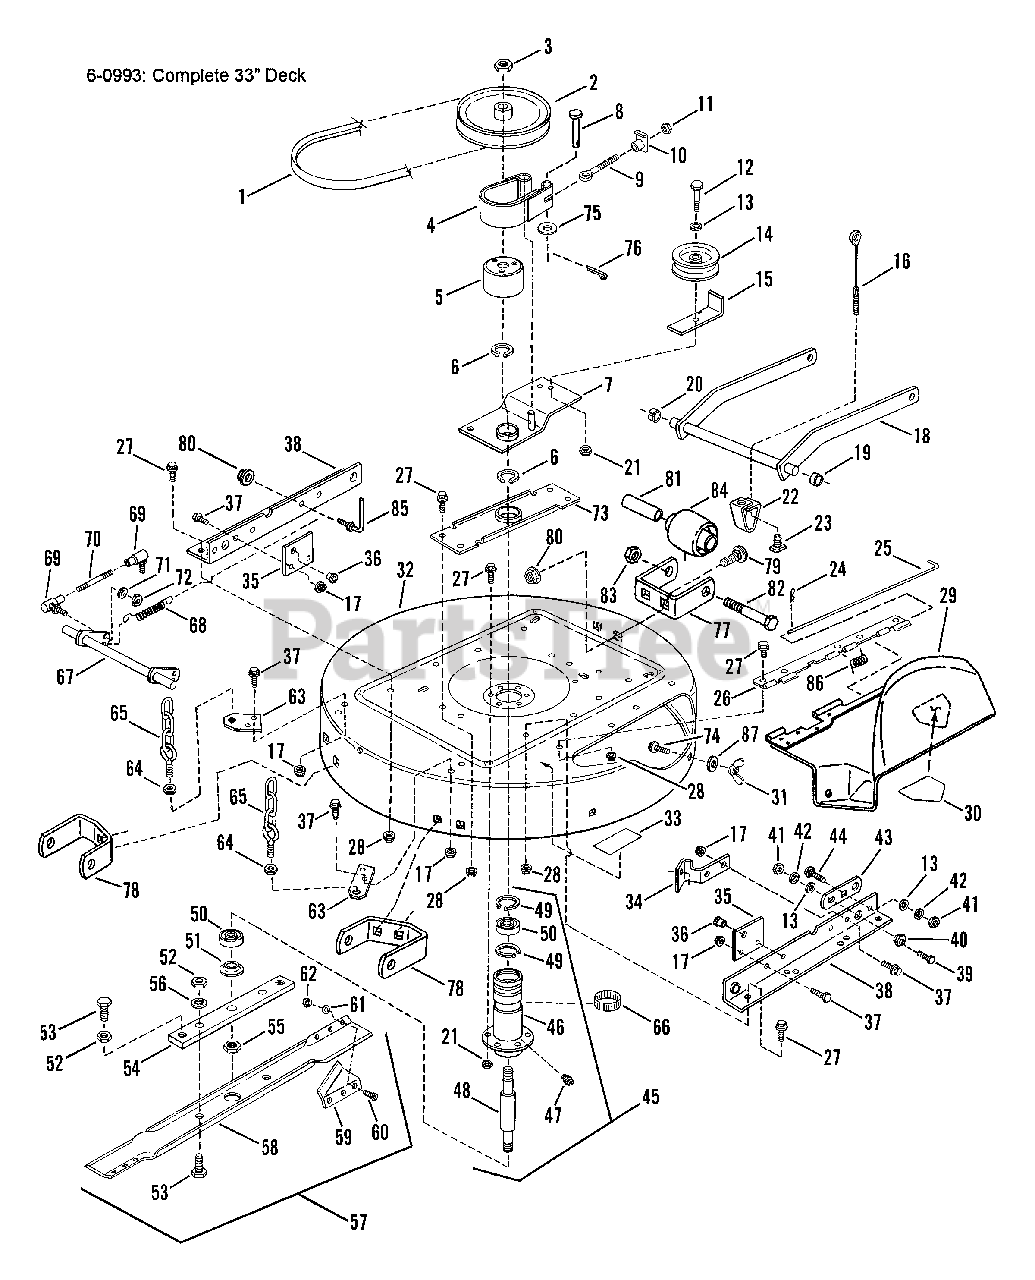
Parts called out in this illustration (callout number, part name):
1	BELT, 33" Drive Kevlar (A-59 61" OD)
2	PULLEY, 8" O.D.
3	NUT, 3/4-16 Hex Jam
4	BAND, Brake Assembly
5	DRUM, Brake
6	RING, 2" External Retaining
7	ARM, Idler
8	PIN, 1/4x1-1/4" Clevis
9	BOLT, 1/4-20 Eye
10	NUT, 1/4-20 Tee
11	NUT, 1/4-20 Hex GR 5 YZ
12	SCREW, 3/8-24x1-1/2" Hex Head Cap
13	WASHER, 3/8 SAE
14	PULLEY, Idler, 4.12 O.D.
15	GUIDE, Belt
16	CABLE, Front Lift 6.12"
17	LOCKNUT, 5/16-18 Hex Flange
18	LIFT, Front Arm
19	RING, Red (Right Side)
20	RING, Black (Left Side)(5/8" ID x .44" Wide)
21	LOCKNUT, 3/8-24 Hex
22	BRACKET, Front Lift Hanger
23	T-NUT, 5/16-18
24	PIN, Hair 3/32" x 1.5"
25	PIN, Hinge
26	HINGE, Deflector
27	BOLT, 3/8-16x3/4" Hex Flange Lock
28	LOCKNUT, 3/8-16 Hex Flange
29	ASSEMBLY, Deflector
30	DECAL, Danger (Cut Finger)
31	WING-NUT, 5/16-18
32	DECK, Cutting, 33"
33	DECAL, Caution (Deflector-Adapter)
34	ANCHOR, Brake
35	BRACKET, Cross-Shaft
36	BEARING, Cross-Shaft Bracket
37	BOLT, 5/16-18x1/2" Hex Flange Lock
38	RAIL, Side
39	SCREW, 3/8-16x1" Hex Head Cap
40	ECCENTRIC, Leveling
41	NUT, 3/8-16 Hex
42	LOCKWASHER, 3/8 Split
43	LINK, Adjustment
44	BOLT, 3/8-16x3/4" Carriage
45	ASSEMBLY, Spindle
46	HOUSING, Spindle 5.575" Tall
47	FITTING, Lube (Press into .187" hole, no ball)
48	SPINDLE, 33" Mower Deck 8.26"
49	RING, Retaining EXT 1.75"
50	BEARING, Spindle
51	WASHER, Spindle
52	NUT, 1/2-20 Hex Jam
53	SCREW, 1/2-20 Hex Head Cap
54	HOLDER, Blade
55	NUT, 5/8-18 Hex Lock
56	WASHER, 1/2 Internal Tooth Lock
58	BLADE, 33" Mower Deck
59	AIR-LIFT
60	SCREW, 5/16-24x11/16" Machine
61	WASHER, 5/16-24 Internal Tooth Lock
62	NUT, 5/16-24 Hex
63	ASSEMBLY, Bracket, Rear Lift
64	NUT, 3/8-16 Hex Jam
65	ASSEMBLY, Bolt-Chain
66	RING, Tolerance 2.0"
67	CROSS-SHAFT
68	SPRING
69	BALL-JOINT
70	LINK, Ball Joint
71	WASHER, 1/4 Internal Tooth Lock
72	NUT, 1/4-28 Hex
73	BRACE, Spindle
74	BOLT, 5/16-18x3/4" Short Neck Carriage
75	WASHER .28 x .63 x .065 YZ
76	COTTER-PIN, 3/32x3/4"
77	BRACKET, Gage Wheel (Front)
78	BRACKET, Gage Wheel (Rear)
79	BOLT, 5/16-18x1/2" Short Neck Carriage
80	NUT, 5/16-18 Hex Flange Lock
81	SPACER .625 OD x .423 ID x 3" L
82	SCREW, 3/8-24x3-3/4" H.H.C.
83	LOCKNUT, 3/8-24 Hex
84	WHEEL, Gage
85	GUIDE, Belt
86	SPRING, Hinge
87	WASHER, 5/16 Flat
